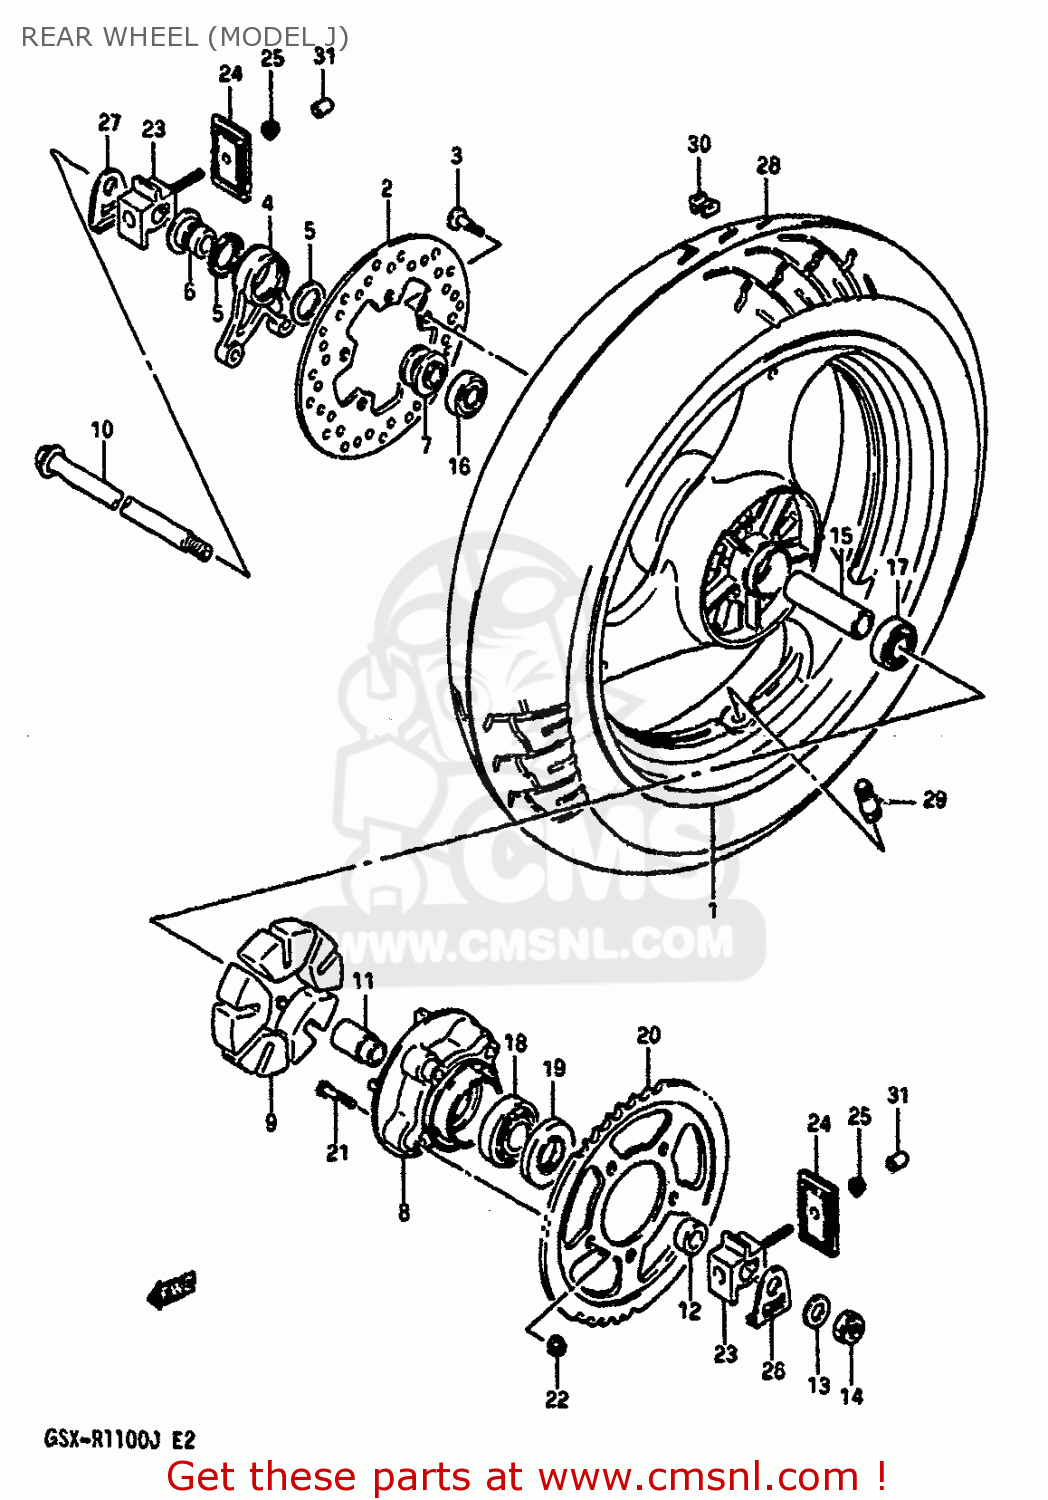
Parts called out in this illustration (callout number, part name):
1	WHEEL,REAR (18XMT4.50)
2	DISC,RR BRAKE
3	BOLT
4	BRACKET,RR CALIPER
5	SEAL,OIL(28X35X5)
6	SPACER,RR CALIPER BRACKET
7	SPACER,RR AXLE,R
8	DRUM,REAR SPROCKET MOUNT
9	ABSORBER,RR HUB SHOCK
10	AXLE,REAR
11	RETAINER,RR HUB BEARING
12	SPACER,RR AXLE,L
13	WASHER
14	NUT 18MM
15	SPACER(20.8X27.2X97)
16	BEARING
17	BEARING(20X47X14)
18	BEARING(25X62X17)
19	SEAL,OIL(35X62X8)
20	SPROCKET,REAR
21	BOLT(10X44)
22	NUT
23	ADJUSTER,CHAIN
24	PLATE,CHAIN ADJUSTER GUIDE
25	NUT
26	WASHER,CHAIN ADJUSTER
27	WASHER,CHAIN ADJUSTER
28	TIRE COMP,TUBELESS 160
29	VALVE,TIRE
30	BALANCER,WHEEL
31	CAP,CHAIN ADJUSTER
32	BALANCER,WHEEL
33	CAP,CHAIN ADJUSTER
